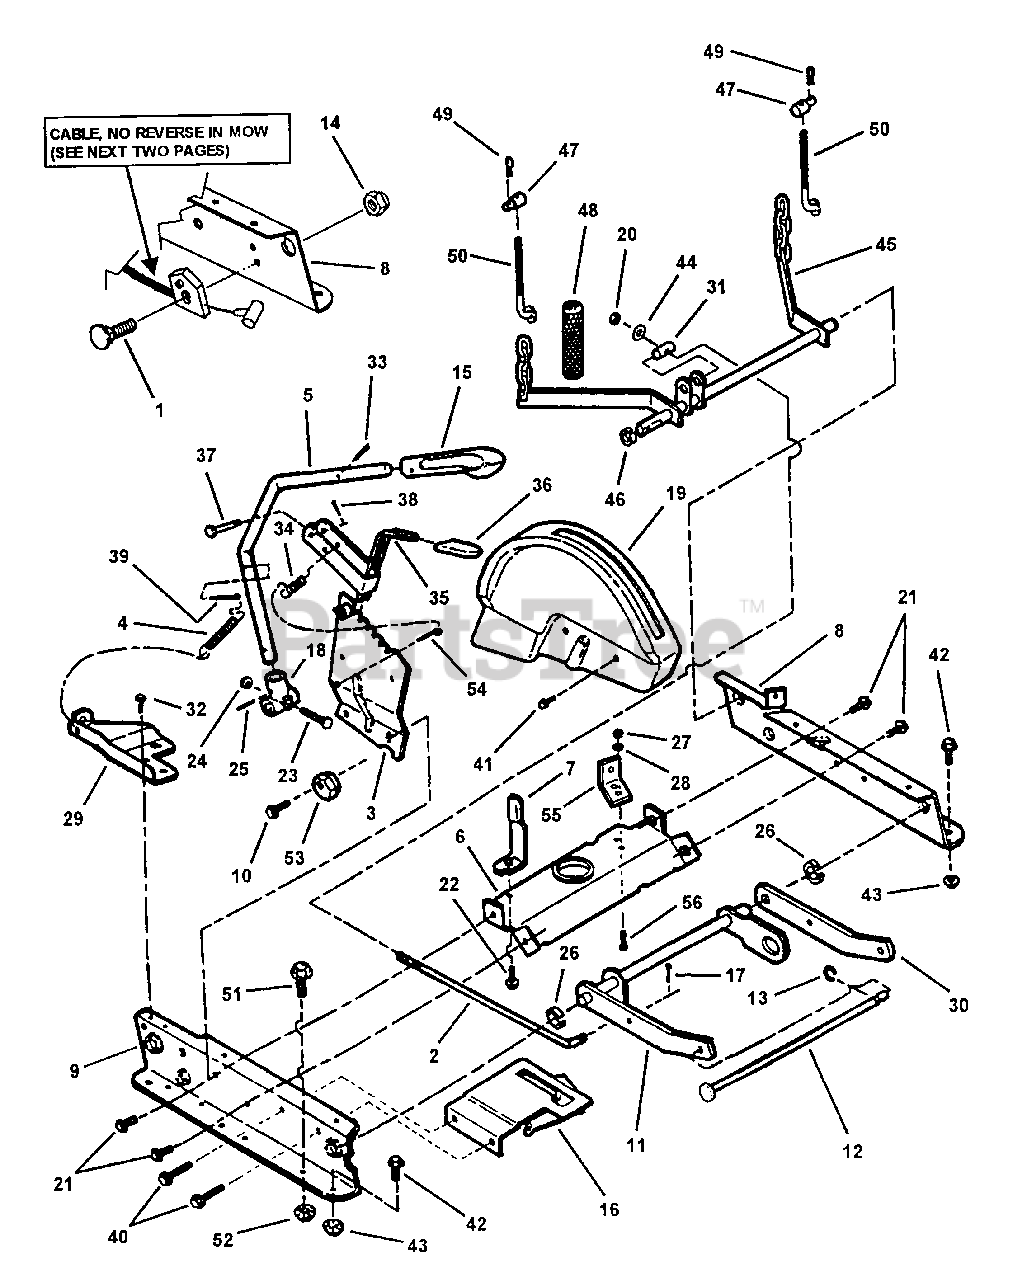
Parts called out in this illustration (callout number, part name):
1	BOLT, #10-24 x 1" Flat Head Square Neck
2	ROD, Leveling
3	QUADRANT, Lift Lever
4	SPRING, Extension
5	LEVER, Lift
6	BRACE, Top
7	GUIDE, Belt
8	RAIL, Left Hand
9	RAIL, Right Hand
10	SCREW, 3/8-16 x 1" Hex Washer Self-Tap
11	ARM, Front Lift, Adjustable
12	ROD, Support
13	SNAP RING, 7/16" External
14	NUT, #10-24 Hex Nyloc
15	GRIP, Height Adjustment Lever
16	ASSEMBLY, Clutch Plate
17	PIN, 1/8 x 3/4" Cotter
18	HUB, Deck Lift
19	COVER, Height of Cut
20	NUT, 3/8-24 Hex Nyloc
21	SCREW, 3/8-16 x 5/8" Hex Washer Self-Tap
22	SCREW, 5/16-18 x 5/8" Hex Washer Self-Tap
23	BOLT, 5/16-24 x 1-5/8" Tapered Axle
24	NUT, 5/16-24 Hex Flange Lock
25	PIN, 3/16 x 1" Roll
26	RING, Red
27	NUT, 5/16-24 Hex
28	WASHER, 5/16 Internal Tooth Lock
29	BRACKET, Lift Assist
30	ARM, Front Lift-Left
31	PIVOT, Leveling
32	SCREW, 1/4-20 x 3/4" Hex Washer Self-Tap
33	PIN, 3/16 x 3/4" Roll
34	SPRING, Latch
35	LATCH (Weldment)
36	GRIP, Lift Latch
37	PIN, 1/4 x 1-1/4" Clevis
38	COTTER-PIN, 1/16 x 3/4"
39	COTTER-PIN, 3/16 x 1-1/2"
40	SCREW, 5/16-18 x 1/2" Hex Washer Self-Tap
41	SCREW, 1/4-20 x 5/8" Hex Washer Self-Tap
42	BOLT, 5/16-18 x 5/8" Hex Flange Lock
43	NUT, 5/16-18 Hex Flange Lock
44	WASHER, 3/8" Flat
45	ARM, Rear Lift
46	RING, Blue
47	SWIVEL
48	COVER, Chain
49	HAIRPIN, 3/32 x 1-1/2"
50	HOOK, Chain
51	BOLT, 1/4-20 x 1/2" Hex Flange Lock
52	NUT, 1/4-20 Hex Flange Lock
53	ECCENTRIC
54	COTTER-PIN, 3/16 x 3/4"
55	ANCHOR
56	SCREW, 5/16-24 x 3/4" Hex Head Cap, Grade 5
